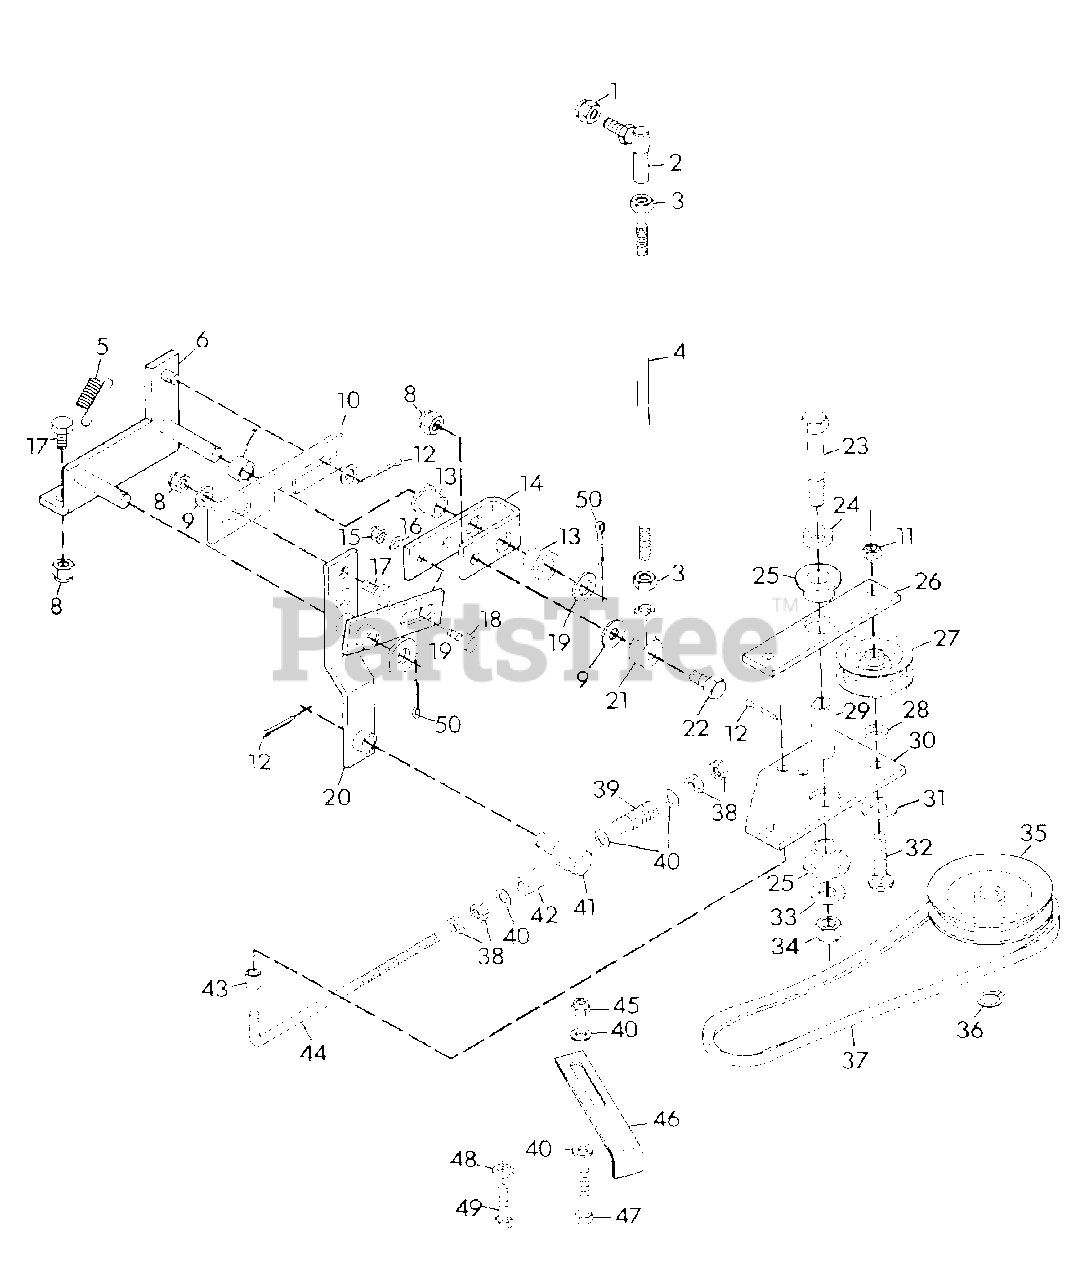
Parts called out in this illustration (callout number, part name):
1	NUT, LOCK 3/8-24
2	BALL JOINT, STEERING
3	NUT, HEX 3/8-24
4	ROD, CLUTCH ACTUATING
5	SPRING, NEUTRAL DETENT
6	WELDMENT, FWD-REV CONTROL BRACKET
7	BUSHING
8	NUT, LOCK 3/8-16
9	WASHER, FLAT .406X.812X.065
10	STRAP, CLUTCH
11	NUT, LOCK 3/8-16
12	PIN, COTTER .09X.75
13	BUSHING, .513X.750X.625
14	LEVER, FWD-REV ACTIVATING
15	NUT, LOCK 1/4-28
16	WASHER, FLAT .281X.625X.065
17	BOLT, HEX 3/8-16X1.00
18	ROLLER, CLUTCH CAM
19	WASHER, FLAT .531X1.062X.095
20	WELDMENT, FWD-REV CAM
21	ROD END, SPHERICAL BEARING
22	BOLT, HEX 3/8-16X1.25
23	BOLT, HEX 1/2-13X3.00
24	SPACER
25	BUSHING, NYLON .76X1X.6 FLANGE
26	PLATE, IDLER
27	SHEAVE, IDLER
28	SPACER, IDLER .406X.750X.188
29	SPACER
30	PLATE, IDLER
31	WASHER, FLAT .531X1.063X.095
32	BOLT, 3/8-16X1.75 RD HD SQ NK
33	WASHER, FLAT .531X1.250X.100
34	NUT, LOCK 1/2-13
35	SHEAVE, TRANSMISSION
36	RING, RETAINING
37	BELT, ENGINE-TRANSMISSION DRIVE
38	NUT, HEX 5/16-18
39	SPRING
40	WASHER, FLAT .344X.688X.065
41	PIVOT
42	BUSHING, NYLON .375X.503X.875
43	BUSHING, .375X.500X.437
44	ROD, CLUTCH
45	NUT, LOCK 5/16-18
46	GUIDE, V-BELT
47	BOLT, HEX 5/16-18X1.75
50	PIN, COTTER .125X1.00
